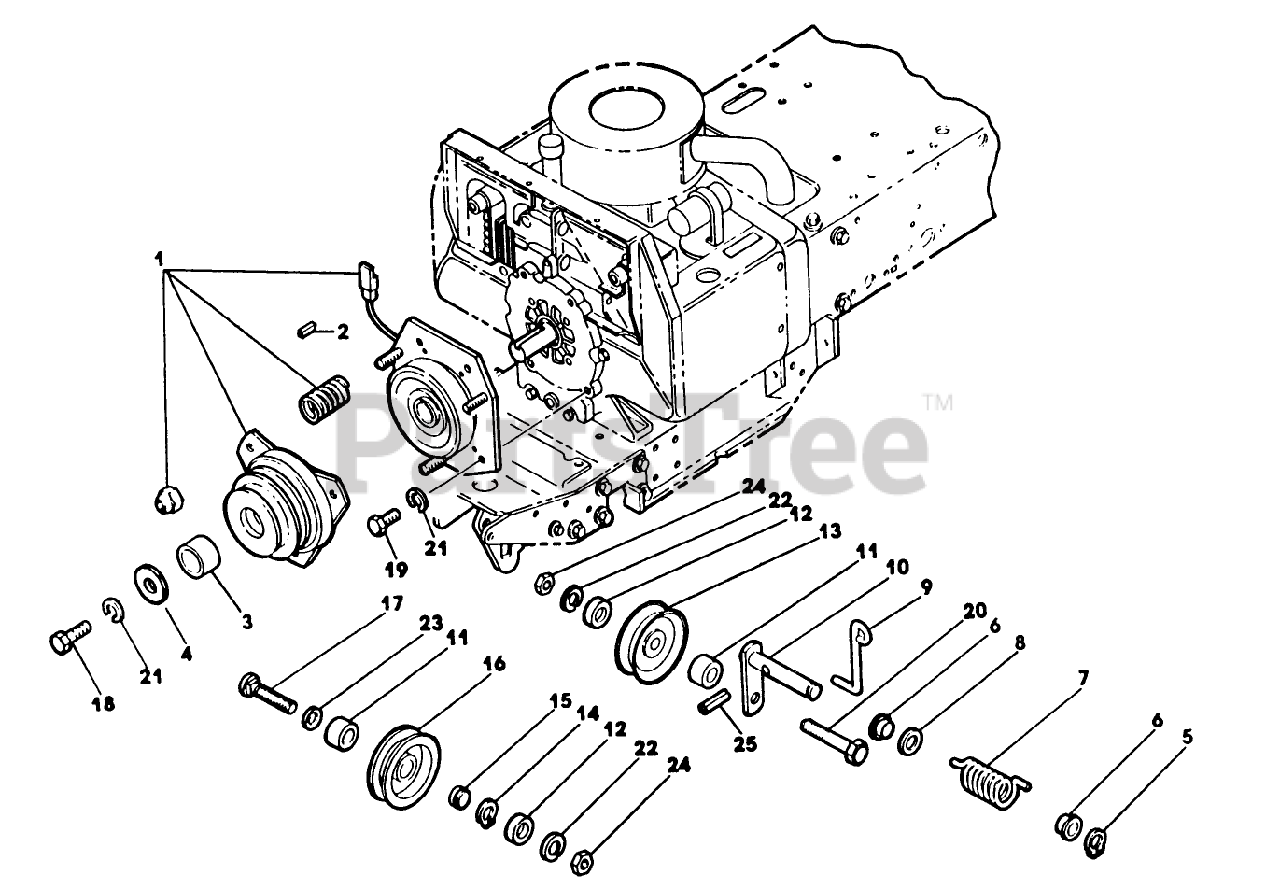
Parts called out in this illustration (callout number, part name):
8	WASHER-SHIM
12	SPACER
13	IDLER PULLEY
14	RING - RETAINING
17	BOLT - CARRIAGE
22	WASHER
